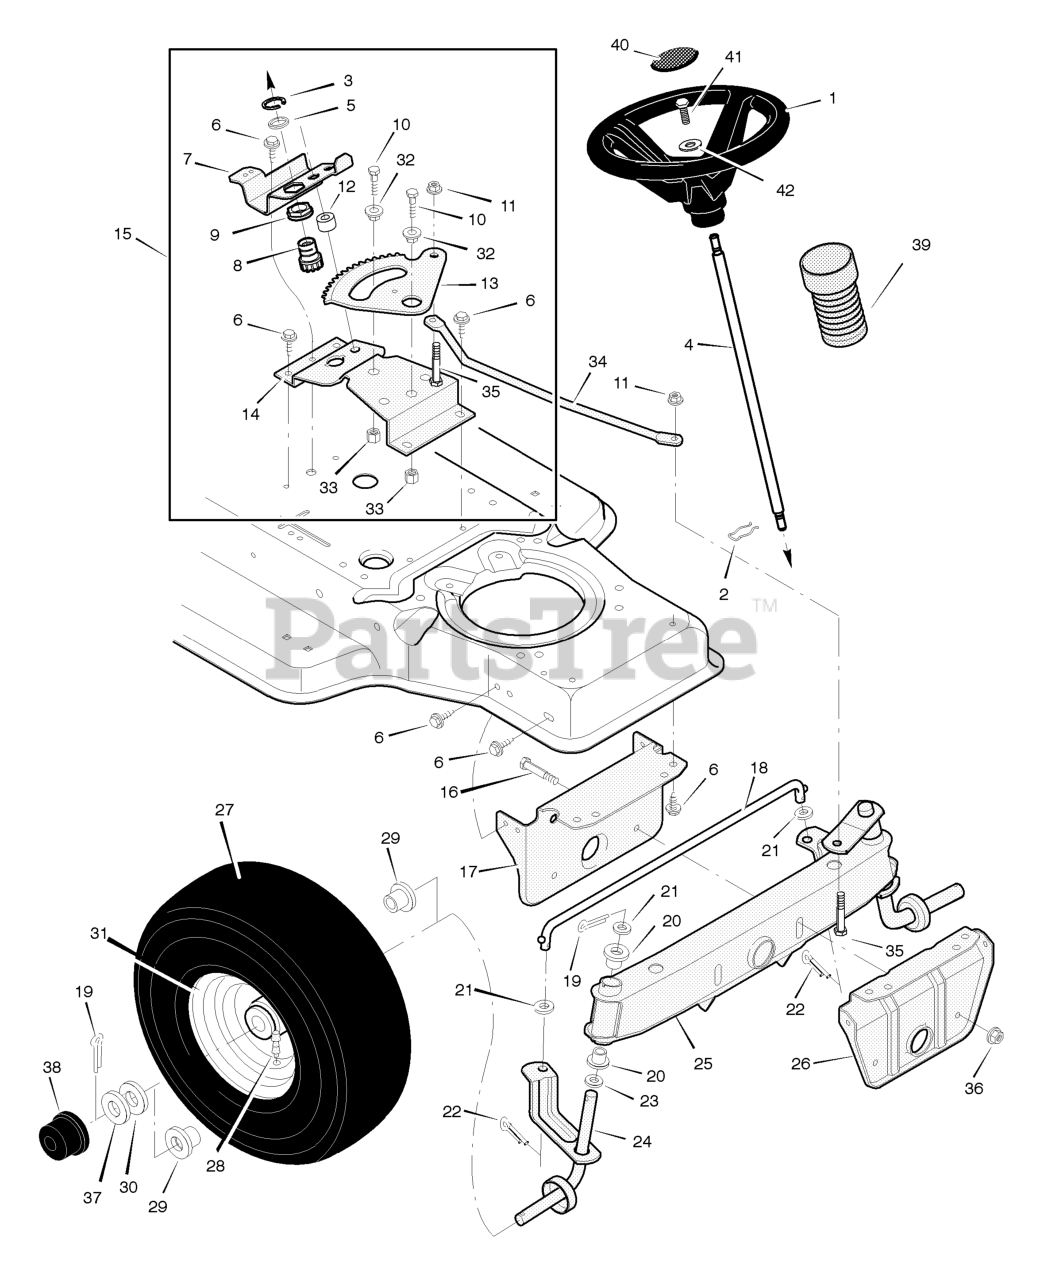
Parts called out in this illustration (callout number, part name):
1	Wheel, Steering
2	Pin, Retainer
3	Ring, E
4	Post, Steering
5	WASHER, 1-1.3 16G FLT
7	Bracket, Sector
8	Gear, Pinion
10	CAPSCREW, Hex Head, 5/16-18 x 1
11	Locknut, Flange
13	Gear, Sector
14	Bracket, Sector
15	Kit, Steering Gear
16	Bolt, Hex
17	Support, Rear Axle
19	Pin, Cotter
20	Bearing
22	Pin, Cotter
24	Spindle Assembly, Right
25	Spindle Assembly, Axle & Left
26	Support, Front Axle
28	Stem, Valve
29	Bearing, Wheel
31	Wheel & Tire Assembly
32	Bearing
33	Locknut, Flange
35	Bolt
36	Locknut, Flange
38	Hub Cap
39	Bellows
40	Cap, Steering Wheel
41	Screw, Hex
42	Washer
